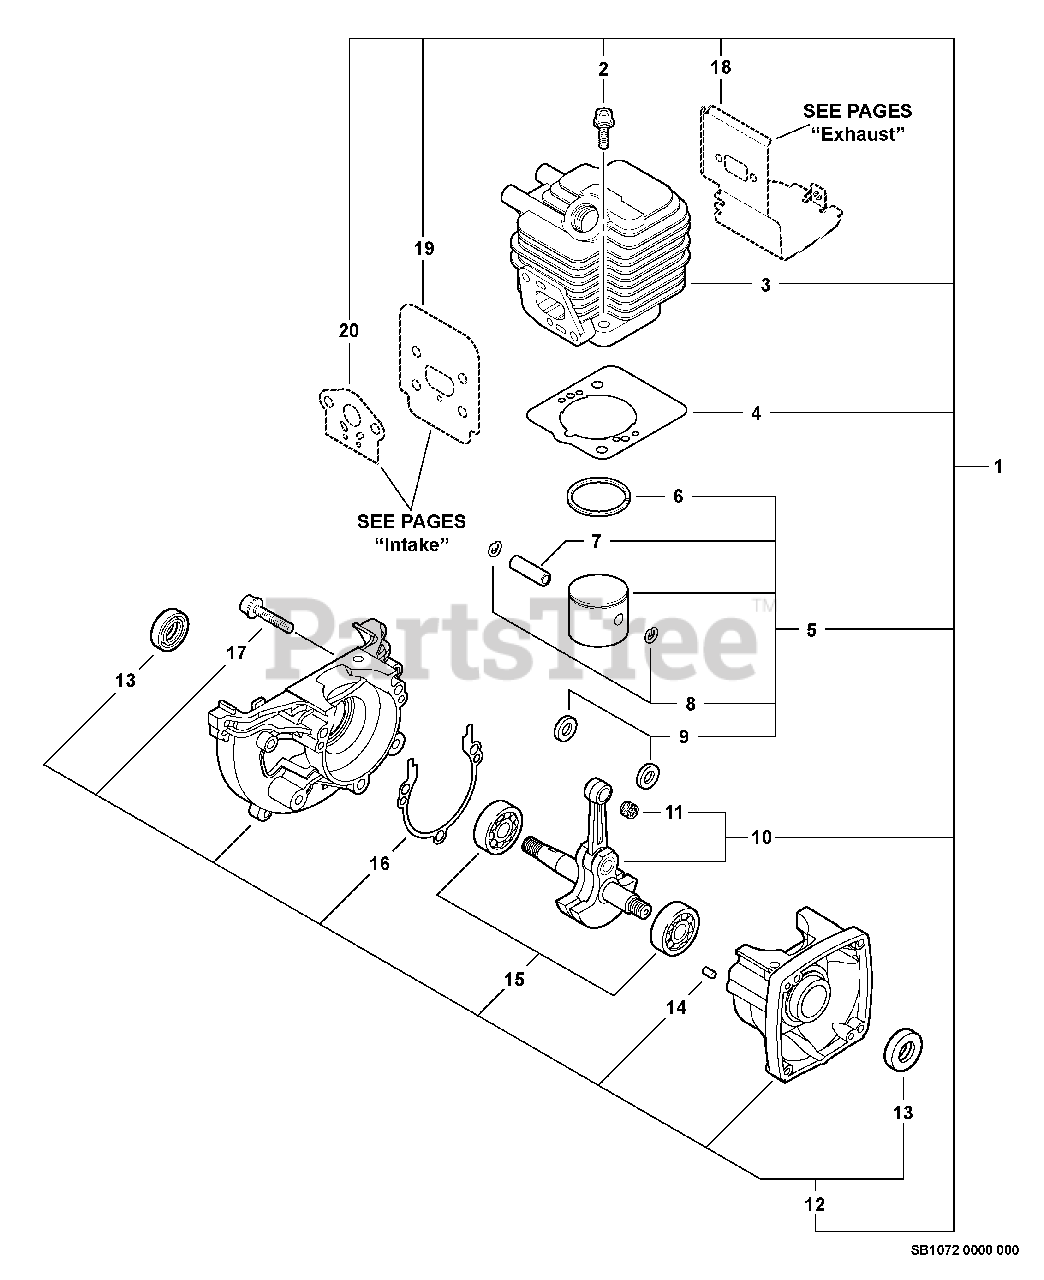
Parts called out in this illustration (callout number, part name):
1	SHORT BLOCK
2	BOLT 5×22
3	CYLINDER
4	GASKET, CYLINDER
5	PISTON KIT
6	RING, PISTON
7	PIN, PISTON 8
8	RING, SNAP
9	WASHER, THRUST
10	CRANKSHAFT ASSY
11	BEARING, NEEDLE 8
12	CRANKCASE KIT
13	SEAL, OIL 12
14	PIN, LOCATING 4
15	BEARING, BALL - 6201 C3
16	GASKET, CRANKCASE
17	BOLT 5×28
18	SHIELD, EXHAUST
19	SHIELD, INTAKE
20	GASKET, INTAKE
